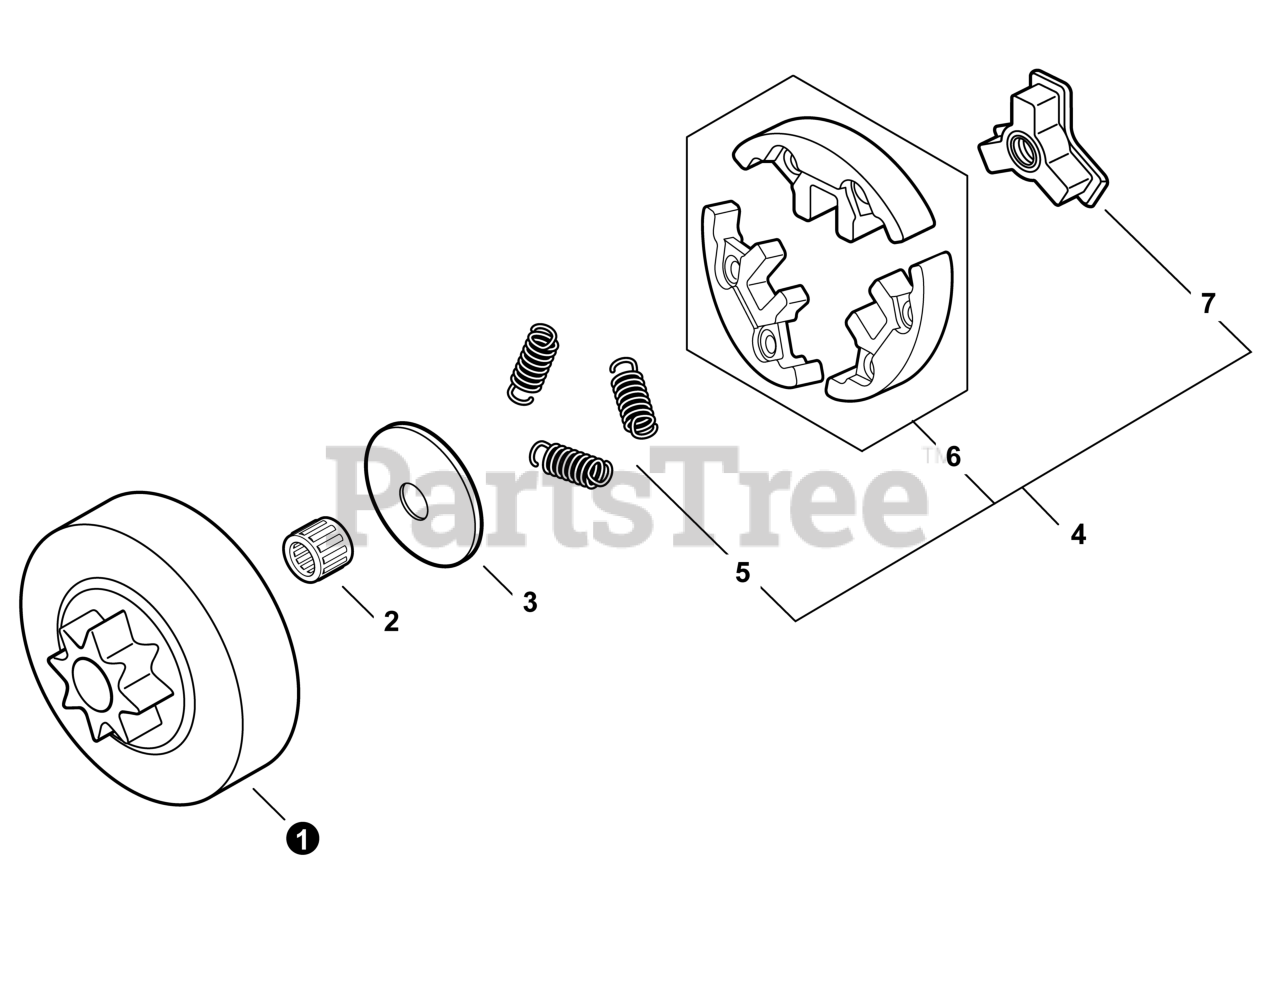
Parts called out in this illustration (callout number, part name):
1	DRUM, CLUTCH
2	BEARING, NEEDLE 10
3	PLATE, CLUTCH
4	CLUTCH ASSY
5	SPRING, TENSION
6	CLUTCH SHOE SET (3PCS)
7	HUB, CLUTCH
